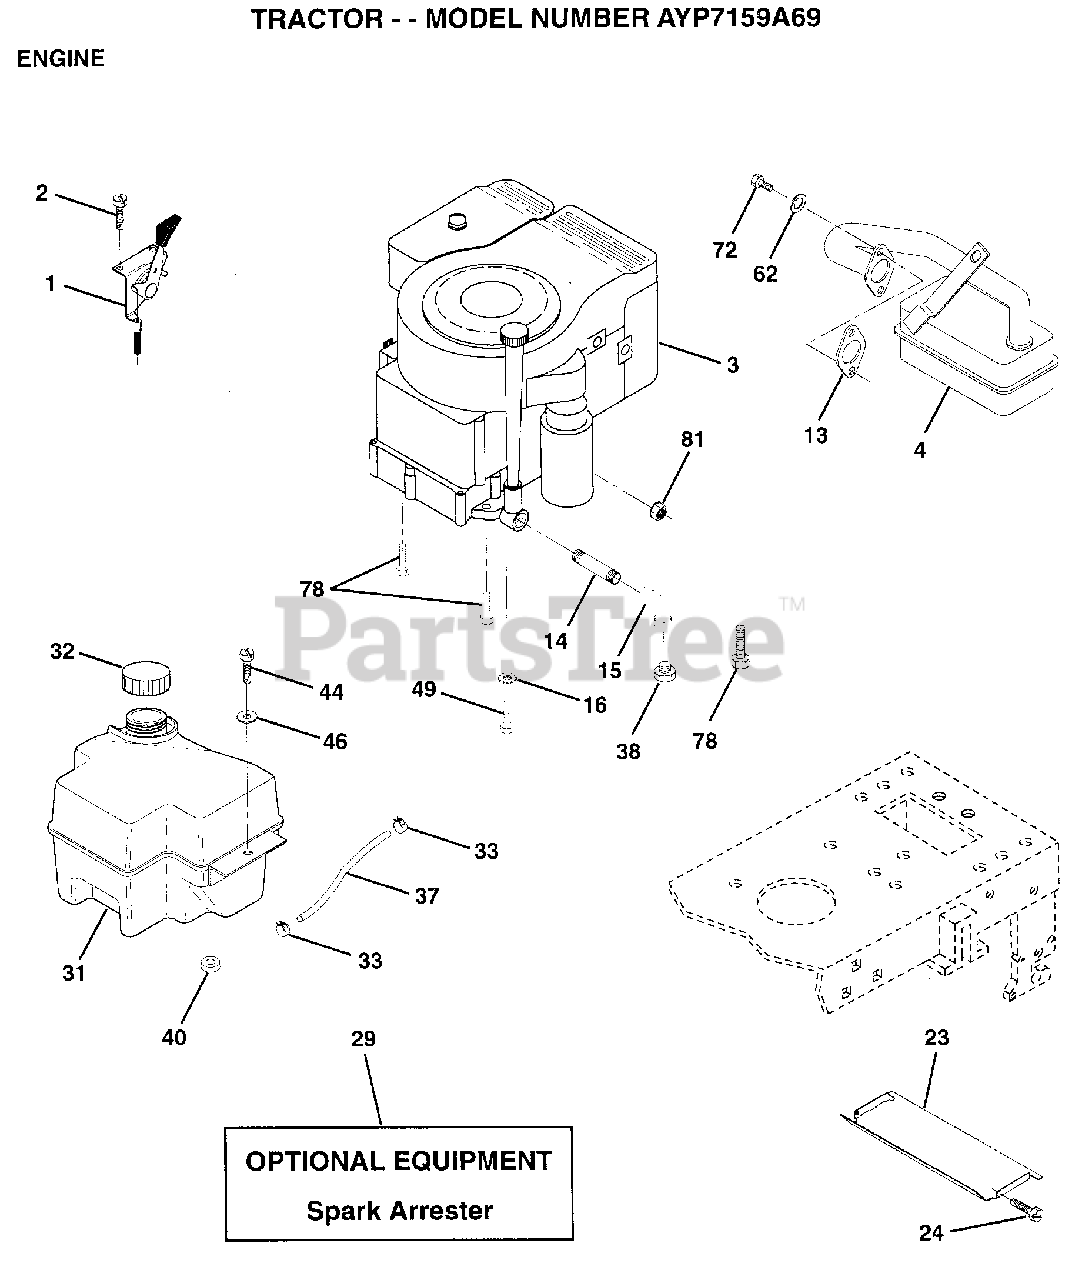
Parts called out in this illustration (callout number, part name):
1	CONTROL THROTTLE
2	SCREW LT
4	MUFFLER
13	GASKET ENG 1 313 LD TIN PLATED
14	PIPE NIPPLE
15	ELBOW
16	LOCKWASHER
23	HEAT SHIELD
24	SCREW
31	CAP ASM FUEL
33	HOSE CLAMP
37	LINE FUEL
44	SCREW HEX CRT
46	WASHER
49	SCREW GTV
62	LOCKWASHER
72	SCREW
78	SCREW
81	NUT
